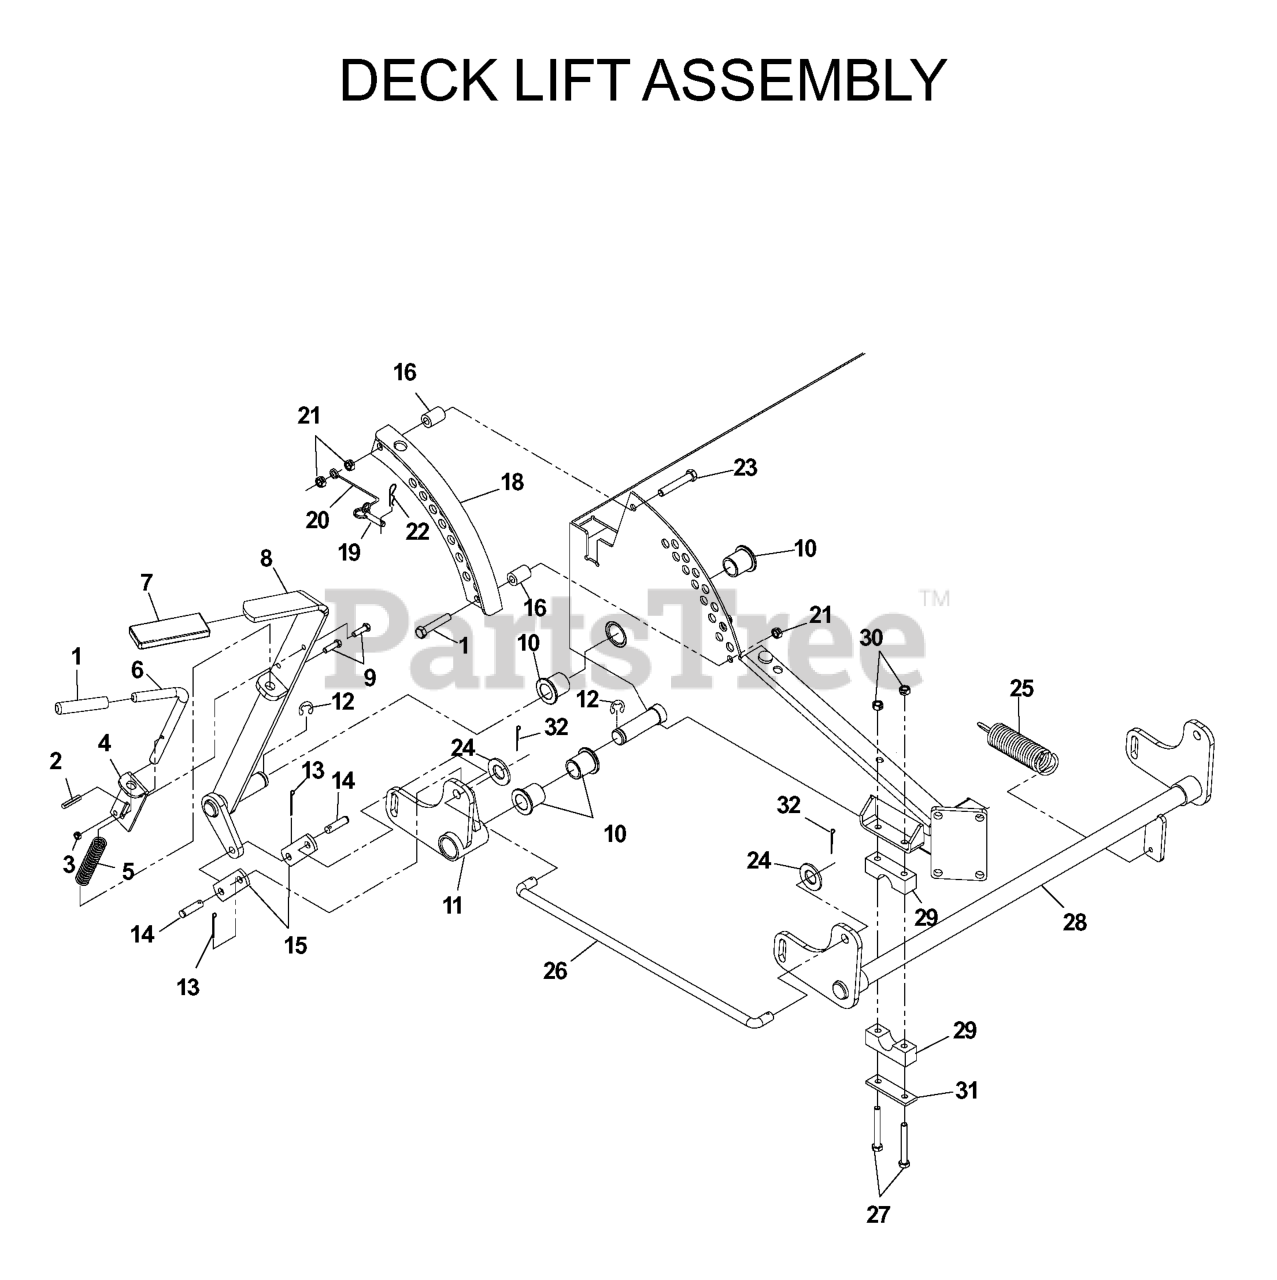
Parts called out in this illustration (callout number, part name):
2	ROLL PIN 3/16 X 1-1/4 ZD
3	NUT 1/4C CENTER LOCK
4	PIN MT, UPPER
8	LEVER WELDMENT
9	HCS 1/4C X 3/4 HCS
10	BUSHING, FLANGED
11	BELLCRANK, RR-BLACK
12	E-RING 7/8
13	RP_COTTER PIN 1/8 X 3/4
14	CLEVIS PIN 3/8 X 1 1/8
17	HCS 3/8C X 2
18	ADJUSTMENT PLATE
21	NUT 3/8-16 NYLOC
22	HAIRPIN #4
23	HCS 3/8C X 2 1/2
26	DECK LIFT LINK
27	HCS 5/16C X 2-3/4
28	LIFT SHAFT
29	PILLOW BLOCK
30	NUT 5/16 NYLOC
31	REINFORCEMENT BAR
32	COTTER PIN
539107031	BELCRANK, LR
